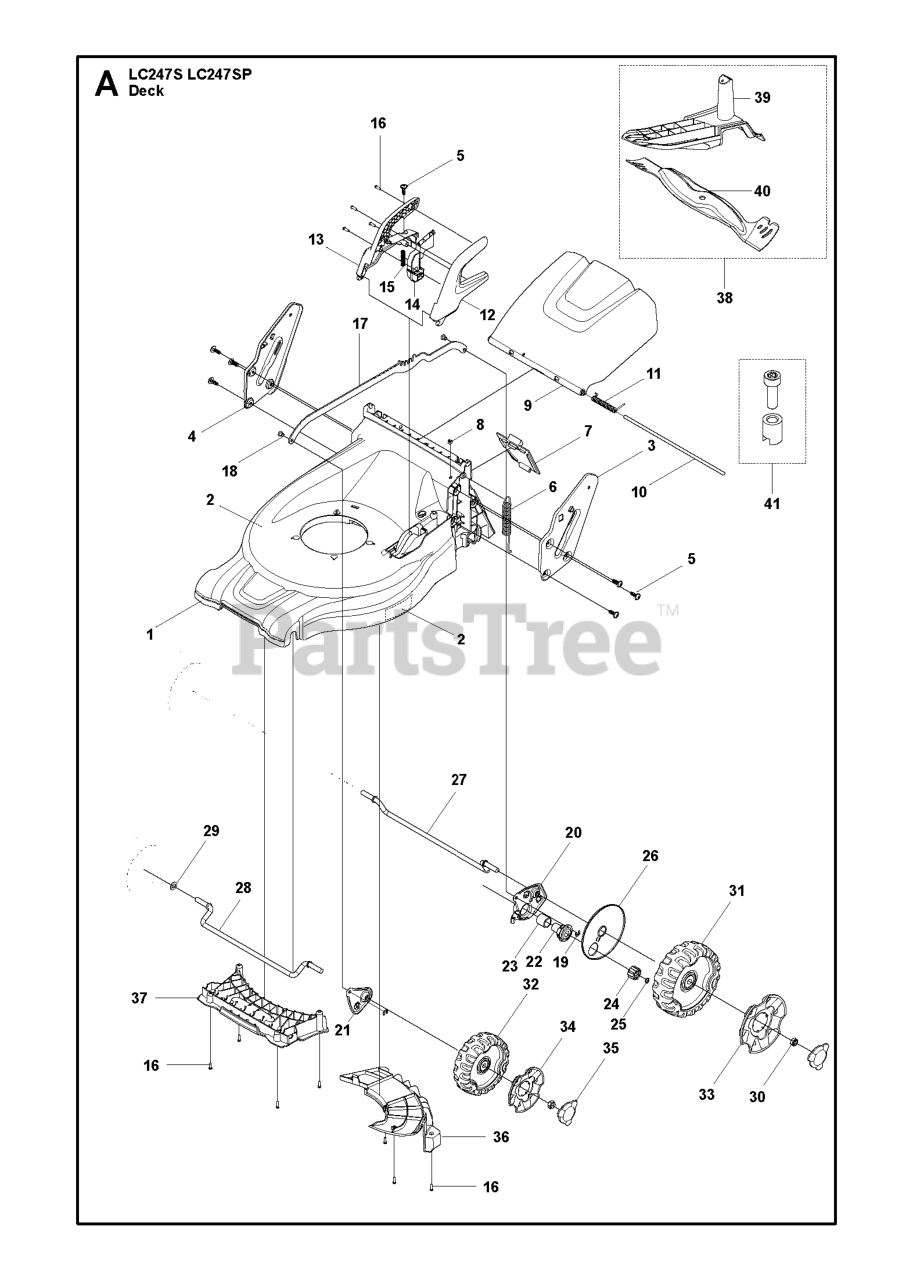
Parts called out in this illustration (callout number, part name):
16	SCREW ITXPANT T50X16 ZN/FE (A
19	Retaining Ring
35	NUT CAP
